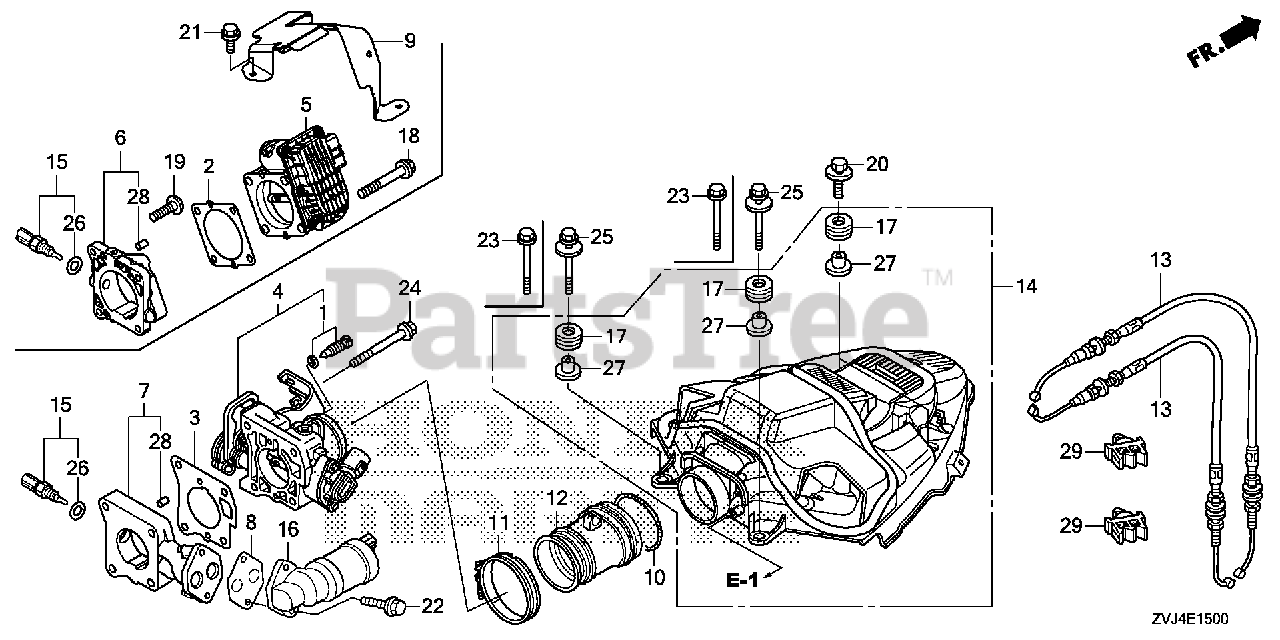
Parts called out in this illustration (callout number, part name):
3	GASKET, THROTTLE BODY
4	BODY ASSY., THROTTLE
7	SPACER, THROTTLE BODY
8	GASKET, EAC VALVE
10	SPRING, AIR FLOW TUBE
11	BAND, AIR FLOW
12	GROMMET, MUFFLER
13	CABLE, THROTTLE
14	COVER ASSY., COOLING FAN
15	SENSOR ASSY., AIR TEMPERATURE
16	VALVE ASSY., EAC
17	GROMMET, CASE (LOWER)
20	BOLT-WASHER (6X25)
22	BOLT, FLANGE (6X22)
24	BOLT, FLANGE (8X65)
25	BOLT-WASHER (6X60)
27	COLLAR, MODULE IGNITION CONTROL CASE (CDI)
28	PIN, DOWEL (6X10)
29	CLIP, BRAKE PIPE
